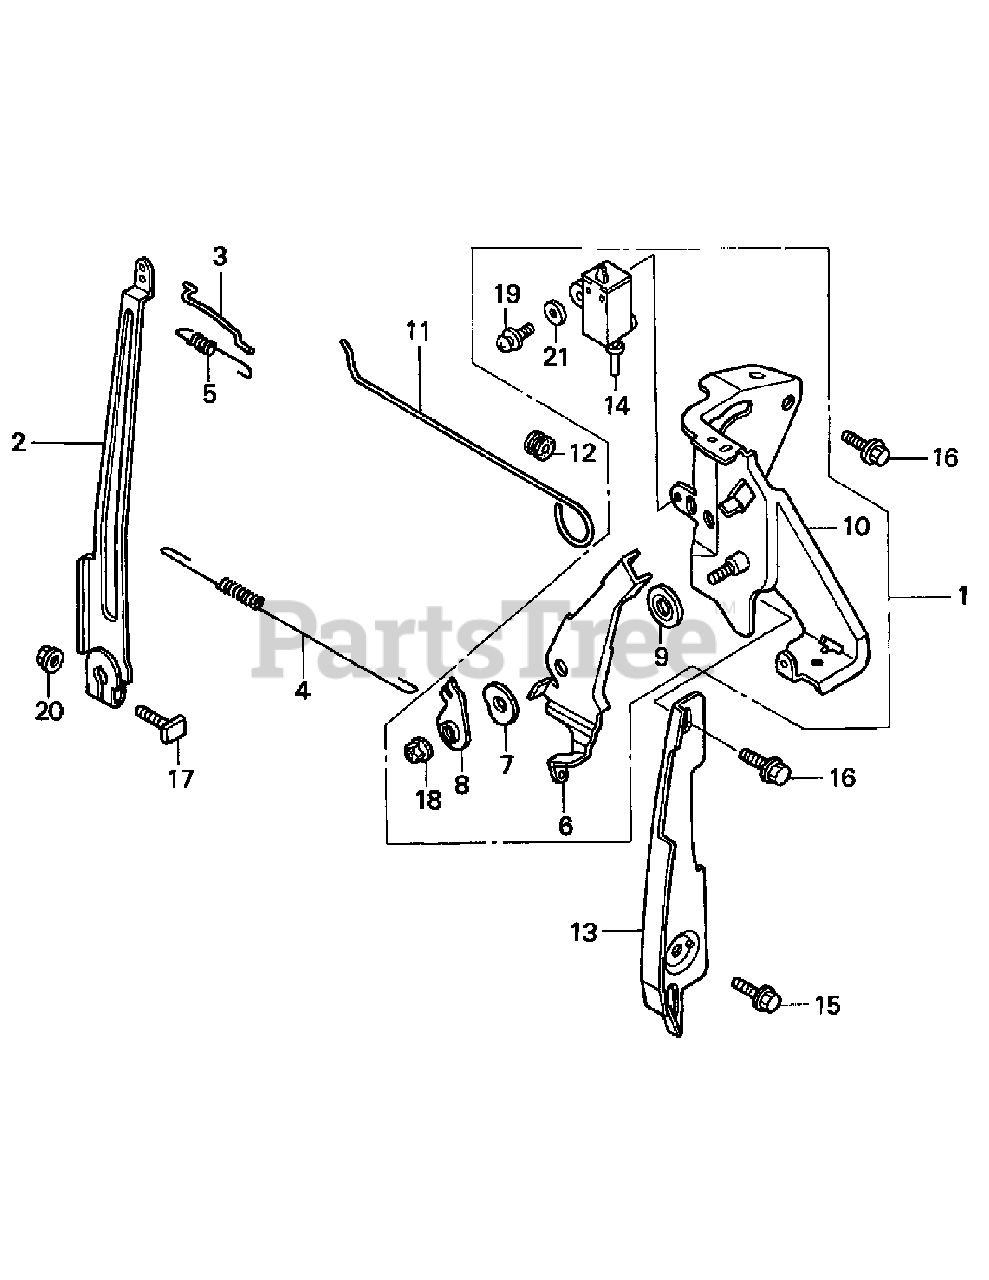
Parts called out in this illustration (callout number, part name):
1	CONTROL ASSY
2	ARM, GOVERNOR
3	ROD, GOVERNOR
4	SPRING, GOVERNOR
5	SPRING, THROTTLE RETURN
6	LEVER, CONTROL
7	SPRING, LEVER
8	WASHER, CONTROL LEVER
9	SPACER, CONTROL LEVER
10	BASE, CONTROL
11	ROD, CHOKE CONTROL
12	GROMMET, CHOKE ROD
13	PLATE, SIDE
14	SWITCH ASSY., ENGINE STOP (N.O)
15	BOLT, FLANGE (6X12) (CT200)
16	BOLT, FLANGE (6X14)
17	BOLT, GOVERNOR ARM
18	NUT, SELF-LOCK (6MM)
19	SCREW-WASHER (4X12)
20	NUT, FLANGE (6MM)
21	WASHER, PLAIN (4MM)
